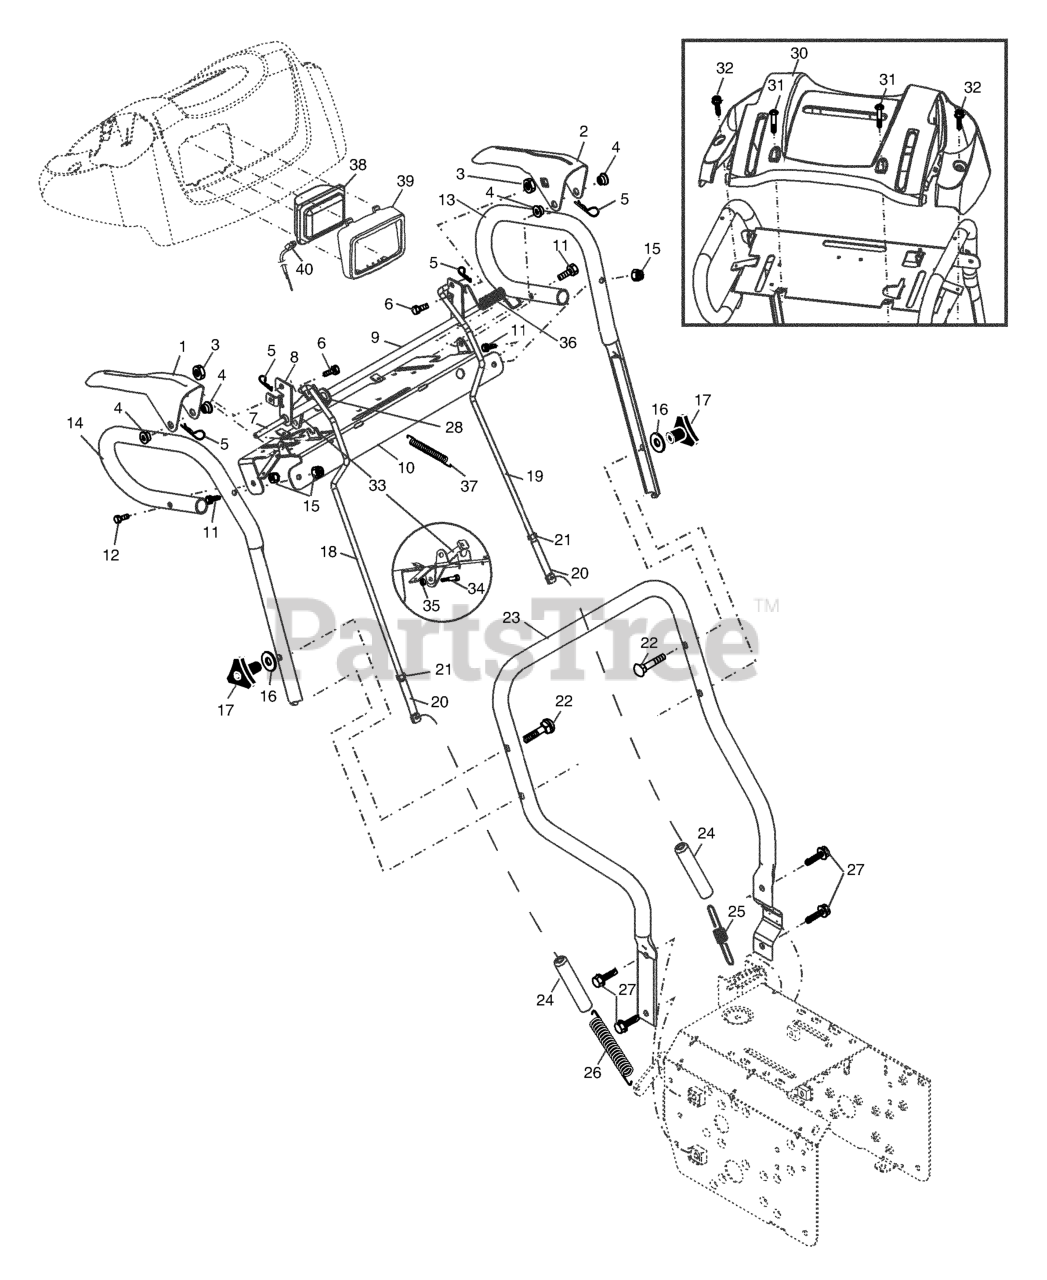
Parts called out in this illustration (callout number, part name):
1	LEVER, AUGER CONTROL
2	LEVER, TRACTION DRIVE CONTROL
3	NUT, CAGE 1/4-20
4	BUSHING, FLANGE
5	SPRING RETAINER
6	SCREW HEX HD 1/4-20 X 3/4
7	ROD.INTERLOCK
8	TUBE ASSM, INTERLOCK
9	TUBE.WELDMENT.INTERLOCK.LH
10	PANEL, CONTROL
11	HEX BOLT
13	HANDLE TUBE LH
14	HANDLE TUBE RH
15	NUT.71038.31-18.HEX.NYLOCK
16	WASHER
17	KNOB.HANDLE.3/8.TRI-POINT.BLAC
18	ROD, AUGER
19	ROD.TRACTION.CONTROL
20	ROD, END CONTROL
21	JAM NUT TI
22	BOLT 3/8-16 X 2-1/4
23	HANDLE TUBE, LOWER (27-30)
24	SLEEVE, SPRING
25	SPRING, TRACTION DRIVE
26	SPRING, AUGER CONTROL
27	Screw, Hex Head 3/8-16 x 1
28	PANEL CLIP
30	PANEL.CONSOLE.SNOW
31	SCREW, HEX HD TAPPING #10-24 1
32	SCREW, HEX HEAD, TAPPING
33	ARM.LATCH.INTERLOCK.YELLOW
34	BOLT, SHOULDER
35	NUT **
36	RP SPRING, TORSION
37	SPRING, INTERLOCK
38	HEADLIGHT.HALOGEN.SNOW
39	BEZEL.HEADLIGHT.BLACK
40	HARNESS.WIRE.HALOGEN
